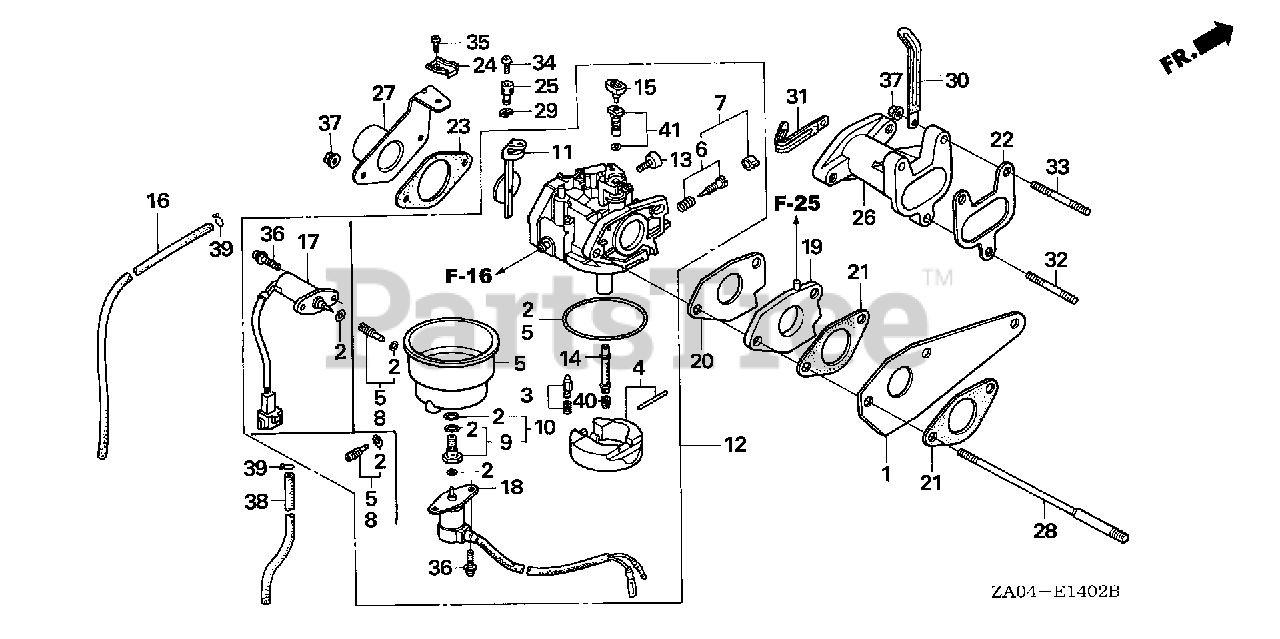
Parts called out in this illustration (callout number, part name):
1	STAY, TIMING BELT
2	GASKET SET (CARBURETOR NO.)
3	VALVE SET, FLOAT
5	CHAMBER SET, FLOAT (CARBURETOR NO.)
6	SCREW SET, PILOT
8	SCREW SET, DRAIN
9	SCREW SET (CARBURETOR NO.)
11	CHOKE SET
12	CARBURETOR ASSY. (BE25A B)
12	CARBURETOR ASSY. (BE25A C)
12	CARBURETOR ASSY. (SPECIAL)
13	SCREW, THROTTLE STOP
14	NOZZLE, MAIN
16	TUBE, AIR VENT
18	VALVE ASSY., SOLENOID (CARBURETOR NO.)
19	INSULATOR, CARBURETOR
20	GASKET, CARBURETOR
21	GASKET, INSULATOR
22	GASKET, IN. MANIFOLD
23	GASKET, AIR CLEANER
24	HOLDER, CONTROL CABLE
25	HOLDER, CABLE
26	MANIFOLD, IN.
27	PIPE, AIR IN.
28	BOLT, STUD (8X100)
29	CIRCLIP (5MM)
30	CLIP, WIRE HARNESS
31	CLIP (2X60)
32	BOLT, STUD (6X18)
33	BOLT, STUD (6X35)
33	BOLT, STUD (6X28)
34	SCREW, PAN (4X8)
35	SCREW, PAN (5X10)
36	SCREW-WASHER (5X12)
37	NUT, FLANGE (6MM)
38	BULK HOSE, FUEL (4.5X3000) (4.5X300)
39	CLIP, TUBE (B8)
40	JET, MAIN (#88)
40	JET, MAIN (#90)
40	JET, MAIN (#92)
41	JET SET, PILOT (#40)
